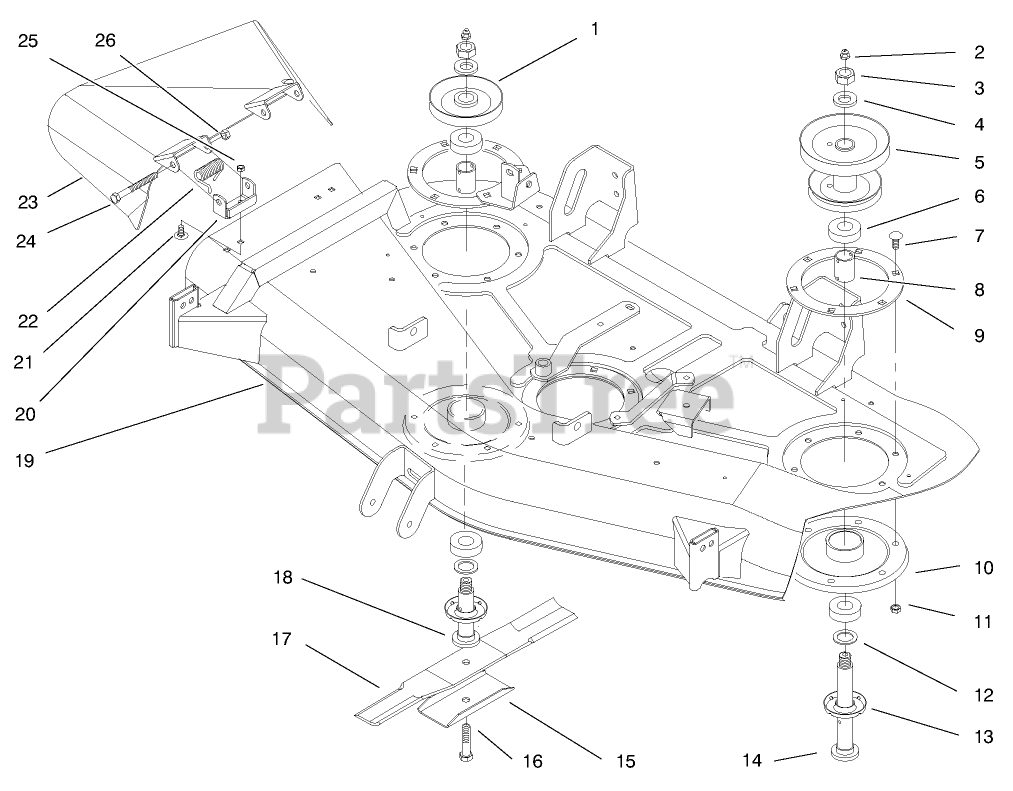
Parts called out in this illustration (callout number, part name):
1	PULLEY
2	FITTING-GREASE
3	NUT-JAM
4	WASHER-FLAT
5	PULLEY-DOUBLE
6	BEARING-BALL
7	SCREW-CARR
8	SPACER-BEARING
9	RING-DECK SUPPORT
11	NUT-HF
12	WASHER-BACKUP
13	SHIELD-BEARING
14	SHAFT - SPINDLE
15	STIFFENER-BLADE
16	SCREW-BLADE
18	SHAFT-SPINDLE
19	DECK ASM
20	BRACKET-PIVOT
21	SCREW-CARR
22	SPRING
24	SCREW-HH
25	NUT-LOCK, NI
26	NUT-HEX
